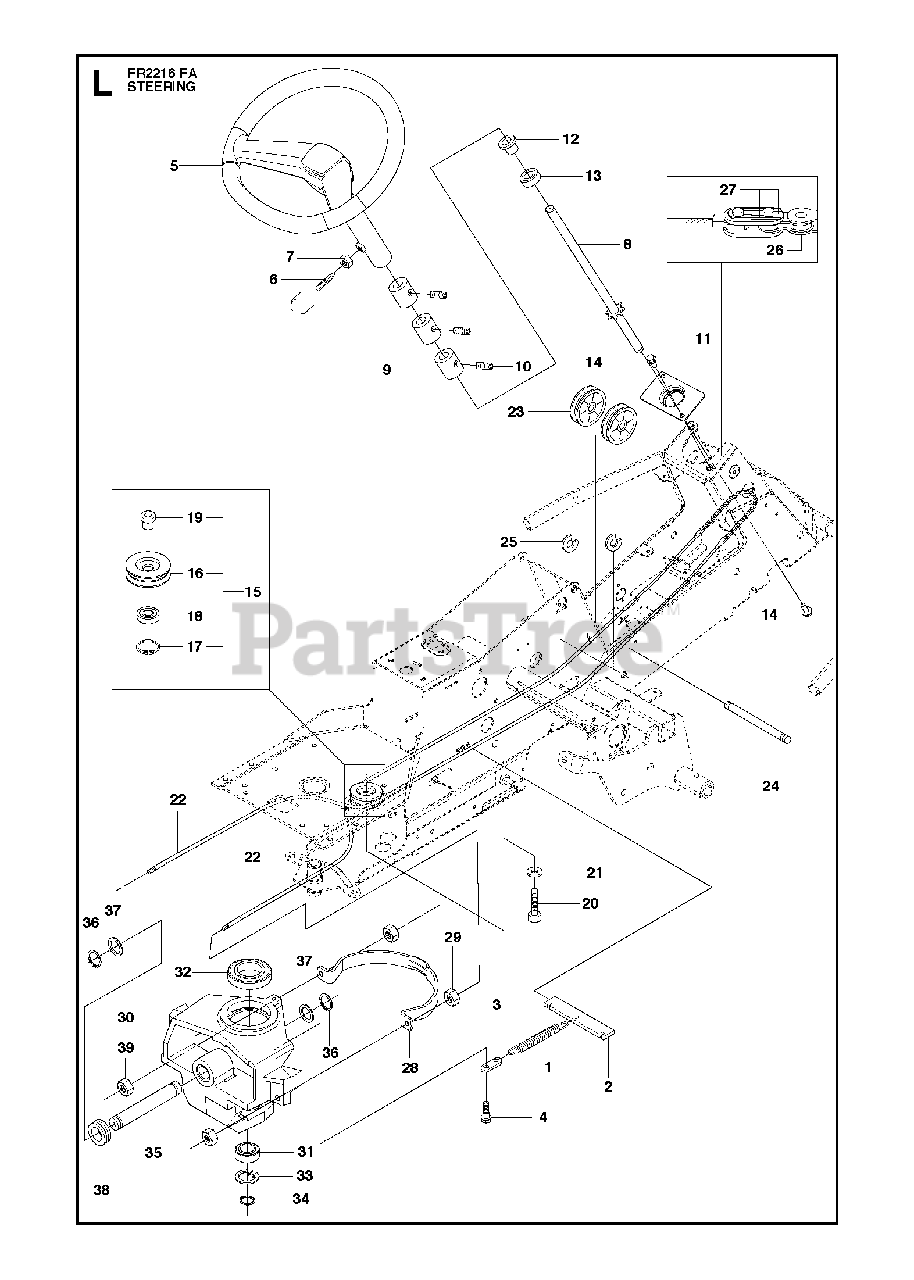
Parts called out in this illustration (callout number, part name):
2	SPRING BRACKET
3	CONNECTOR
5	STEERING WHEEL
7	NUT
8	ROD STEERING ASSY
13	BALL BEARING 6004-2RS1
16	ROLLER
17	CIRCLIP SGH 47
18	BALL-BEARING 6204-2RS
19	BUSHING
20	COLLAR SCREW
22	RP STEERING CABLE COMPLETE
25	RETAINING RING
26	STEERING CHAIN
28	WIRE GUIDE
31	BALL BEARING 6005-2RS
32	BALL BEARING 6010 2RS1
33	CIRCLIP SGH 47
34	RETAINING RING SGA 25
36	RETAINING RING SGA 25
